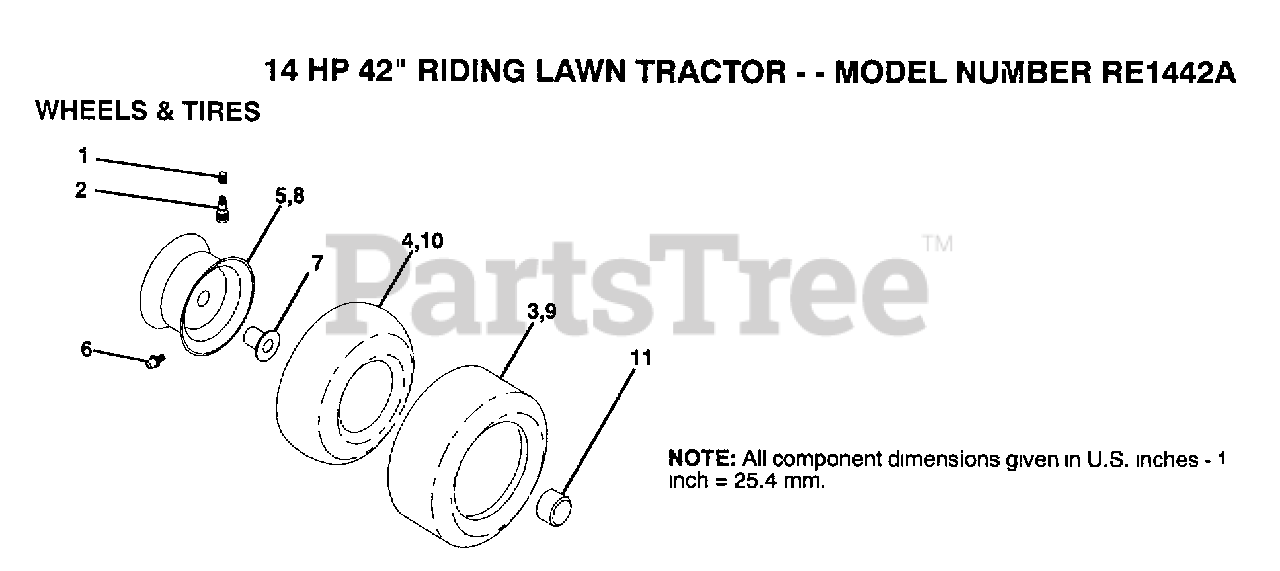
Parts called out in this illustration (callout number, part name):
1	VALVE CAP
2	VALVE STEM LT
4	TUBE.5.3/4.5/6
6	FITTING LT
7	"FLANGE, BEARING"
10	TUBE.18X9.5-8
11	HUB CAP
